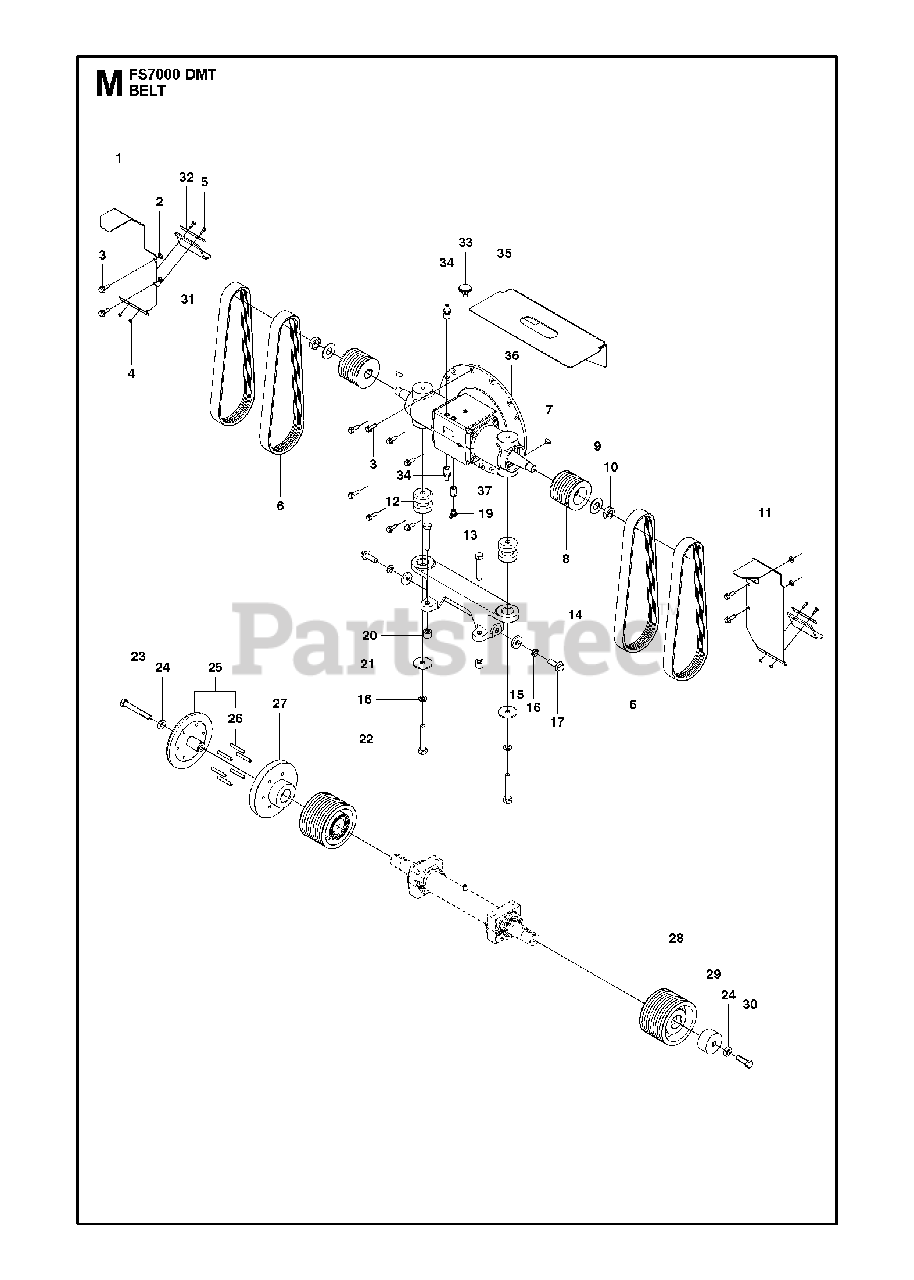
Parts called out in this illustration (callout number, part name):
2	WASHER
4	HEXAGON LOCKING NUT
12	ANTIVIBRATION ELEMENT
